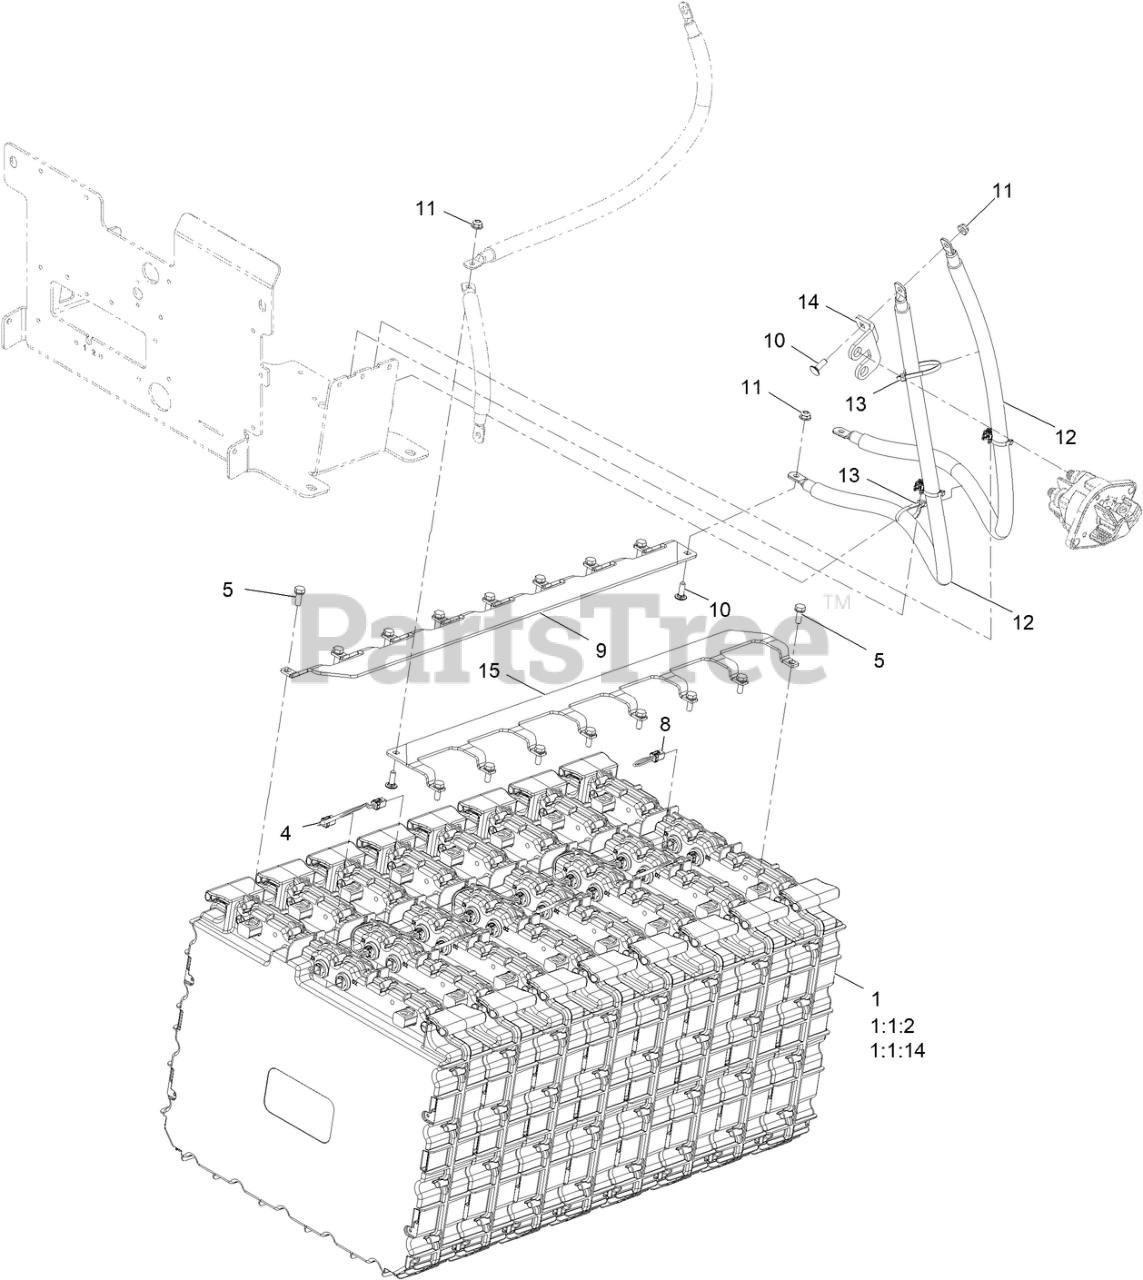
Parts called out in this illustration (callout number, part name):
1	BATTERY ASM
1:1:2	DECAL-WARNING, BATTERY
1:1:14	NUT-MOUNTING, JWPF PANEL LOCK
4	HARNESS-WIRE, DATA INTERFACE
5	SCREW-SEMS
8	HARNESS-WIRE, CAN TERMINATOR
9	BUSBAR-8, RD
10	BOLT-CARR
11	NUT-HF
12	CABLE-BATTERY,RD ASM
13	TIE-CABLE
14	BUSBAR-2, SWITCH
15	BUSBAR-8, BK
